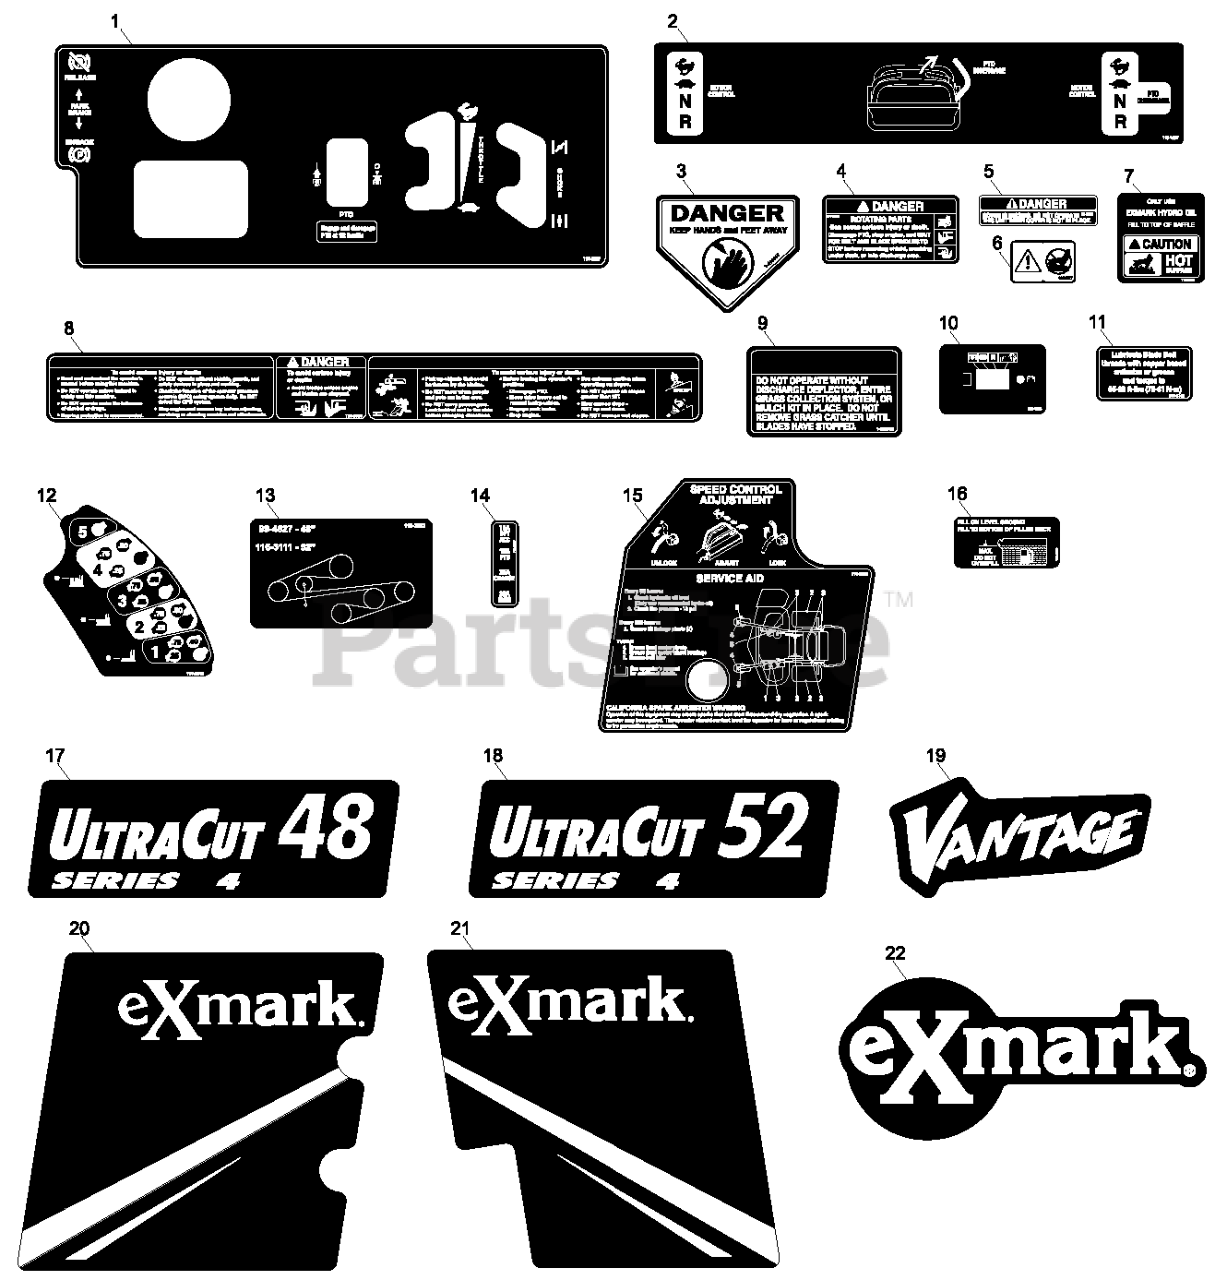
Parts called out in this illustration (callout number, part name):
2	DECAL-MOTION CONTROL
3	DECAL-DANGER
4	DECAL-ROTATING PARTS
5	DECAL-COVER, MISSING
6	DECAL-WARNING
7	DECAL-HYDRAULIC TANK
9	DECAL-WARNING, DISCHARGE
10	Decal, Hour Meter
11	DECAL,BOLT TORQUE
12	DECAL-HEIGHT OF CUT
13	DECAL-BELT ROUTING
14	DECAL-FUSE
16	DECAL-FILL, FUEL
17	DECAL,ULTRACUT 48 SERIES
18	DECAL,ULTRACUT 52 SERIES
19	DECAL-VANTAGE LOGO
21	DECAL-RH PANEL
22	DECAL, EXMARK LOGO
